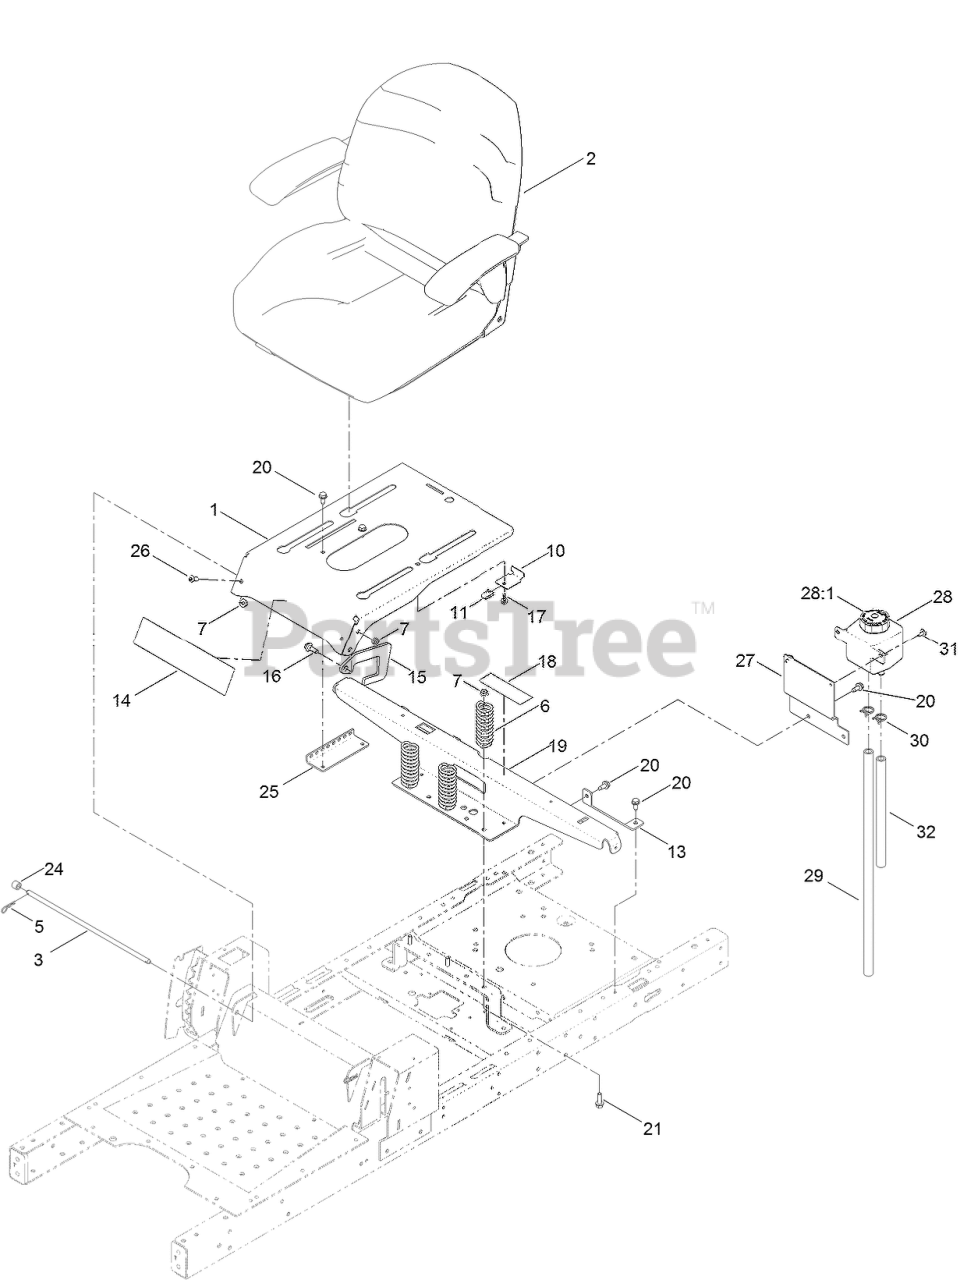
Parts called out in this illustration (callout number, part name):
1	PAN-SEAT
2	SEAT ASM
3	ROD-STOP
5	PIN-COTTER
6	SPRING-COMPRESSION
7	NUT-HF, NI
10	BRACKET-STOP, SEAT
13	SUPPORT-TANK, REAR
14	DECAL-TIMECUTTER
15	PLATE-STOP
16	SCREW-SHOULDER
17	SCREW-HHF
18	DECAL-SERVICE, CE
19	SUPPORT-POD, WIDE
20	SCREW-HWHTF
21	SCREW-HHF
24	BUSHING-LEVER, LIFT
25	BRACKET-LATCH, SEAT
26	SCREW-HSBH
27	MOUNT-TANK
28	VENT-TANK, HYD
28:1	CAP-RESERVOIR, HYD
29	HOSE-OVERFLOW
30	CLAMP-HOSE
31	SCREW-HHFTF
32	HOSE-OVERFLOW
